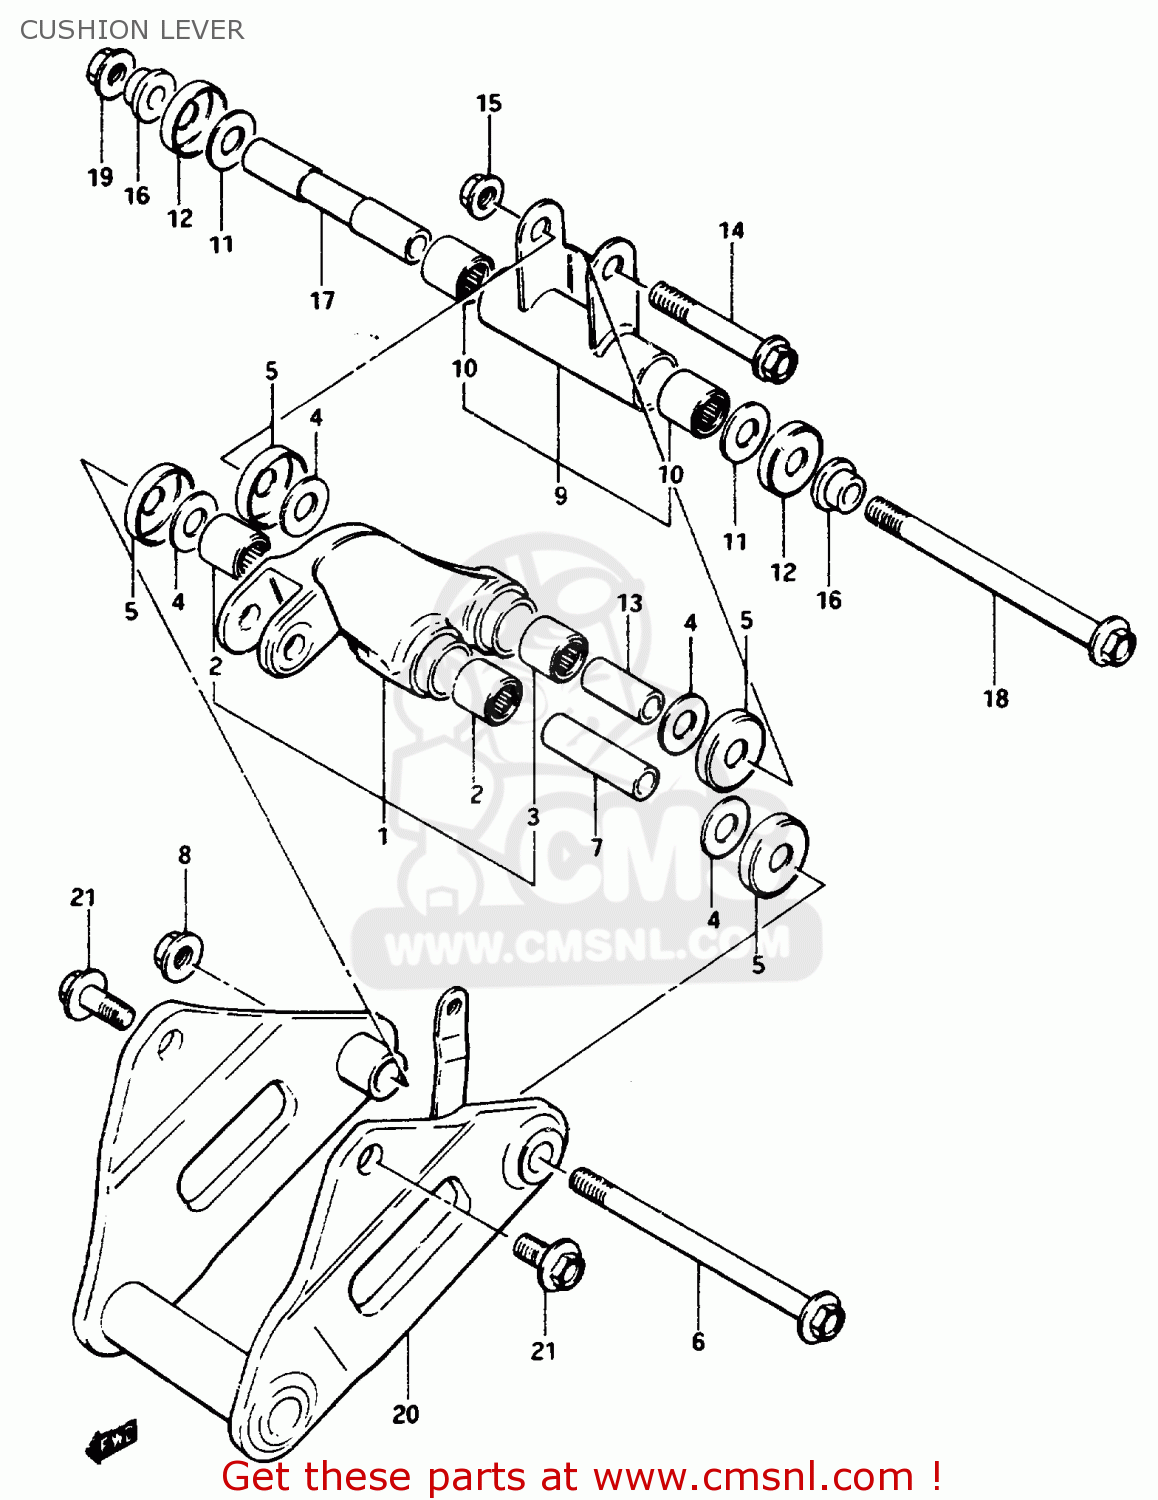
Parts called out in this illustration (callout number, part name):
1	LEVER SET,REAR CUSHION
2	ROLLER BEARING (17X24X2
3	ROLLER BEARING (17X24X25)
4	WASHER
5	COVER,RR SWGARM DUST SEAL
6	BOLT,CUSHION ROD
7	SPACER,REAR CUSHION LEVER
8	NUT 12MM
9	ROD SET,REAR CUSHION,LEFT
10	ROLLER BEARING (17X24X2
11	WASHER
12	COVER,RR SWGARM DUST SEAL
13	SPACER,RR CUSHION LEVER ROD UP
14	BOLT, UPPER
15	NUT 12MM
16	SPACER,REAR CUSHION ROD
17	SPACER,RR CUSHION LVR ROD LOW
18	BOLT,CUSHION ROD
19	NUT 12MM
20	BRACKET,REAR SHOCK ABSORBER
21	BOLT,REAR SHOCK ABSORBER BRACKET
